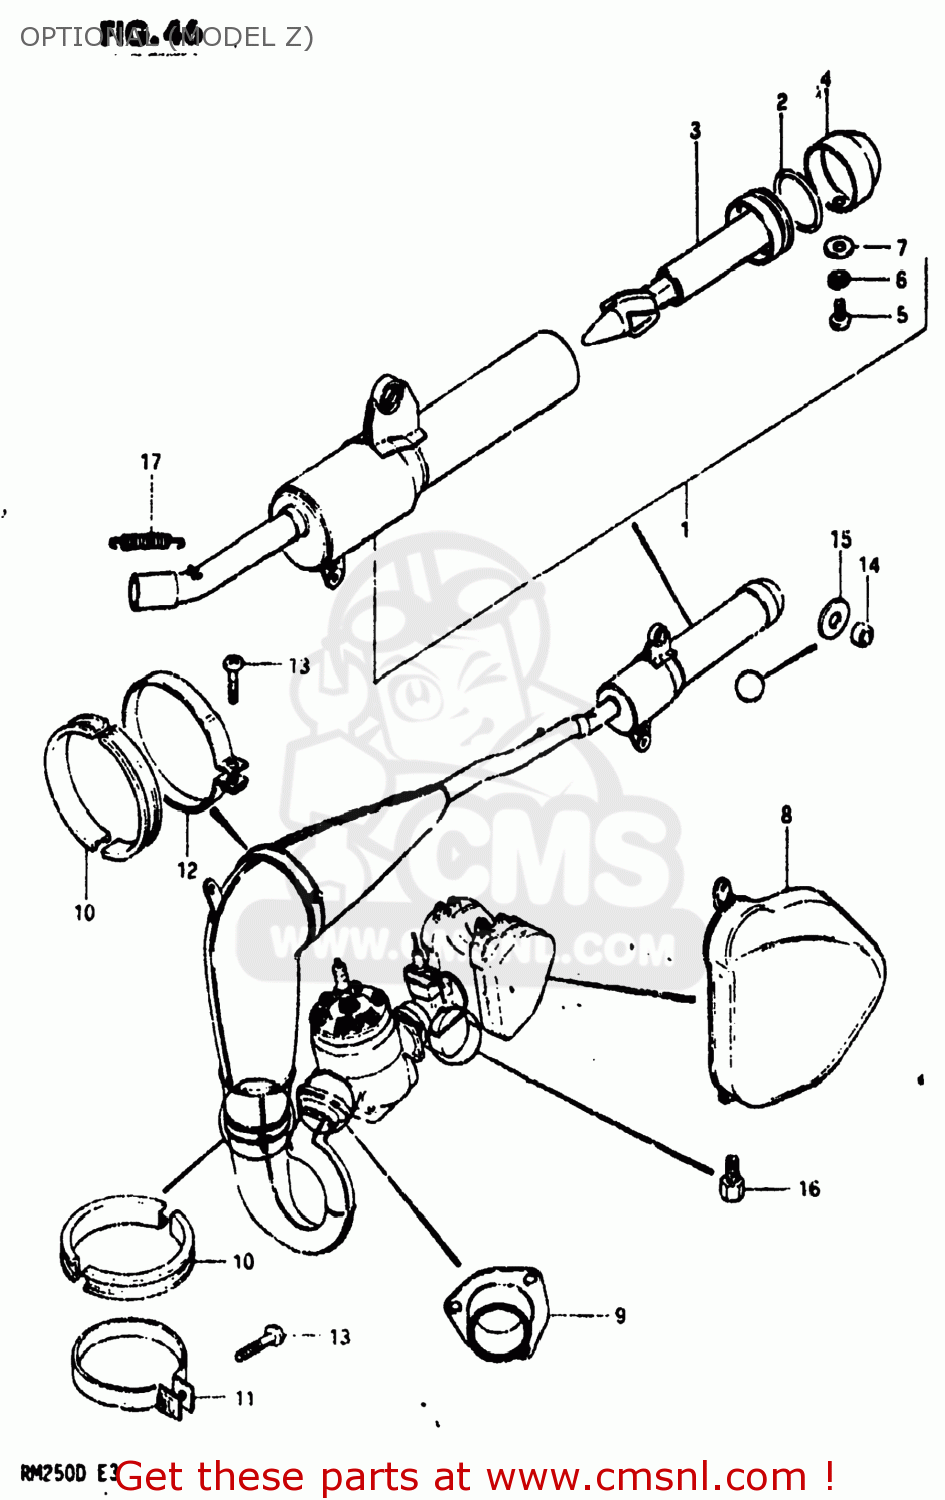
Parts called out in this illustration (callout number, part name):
1	MUFFLER ASSEMBLY
2	O-RING (D:3.5 ID:54.4)
3	TUBE,MUFFLER CLEAN OUT
4	COVER,SECOND MUFFLER TAIL
5	SCREW(6X8)
6	LOCK WASHER
7	WASHER
8	COVER AIR CLEANER
9	FLANGE,EXHAUST PIPE
10	BODY,MUFFLER
11	CLAMP
12	CLAMP
13	SCREW
14	SPACER
15	GASKET
16	JET
17	SPRING
